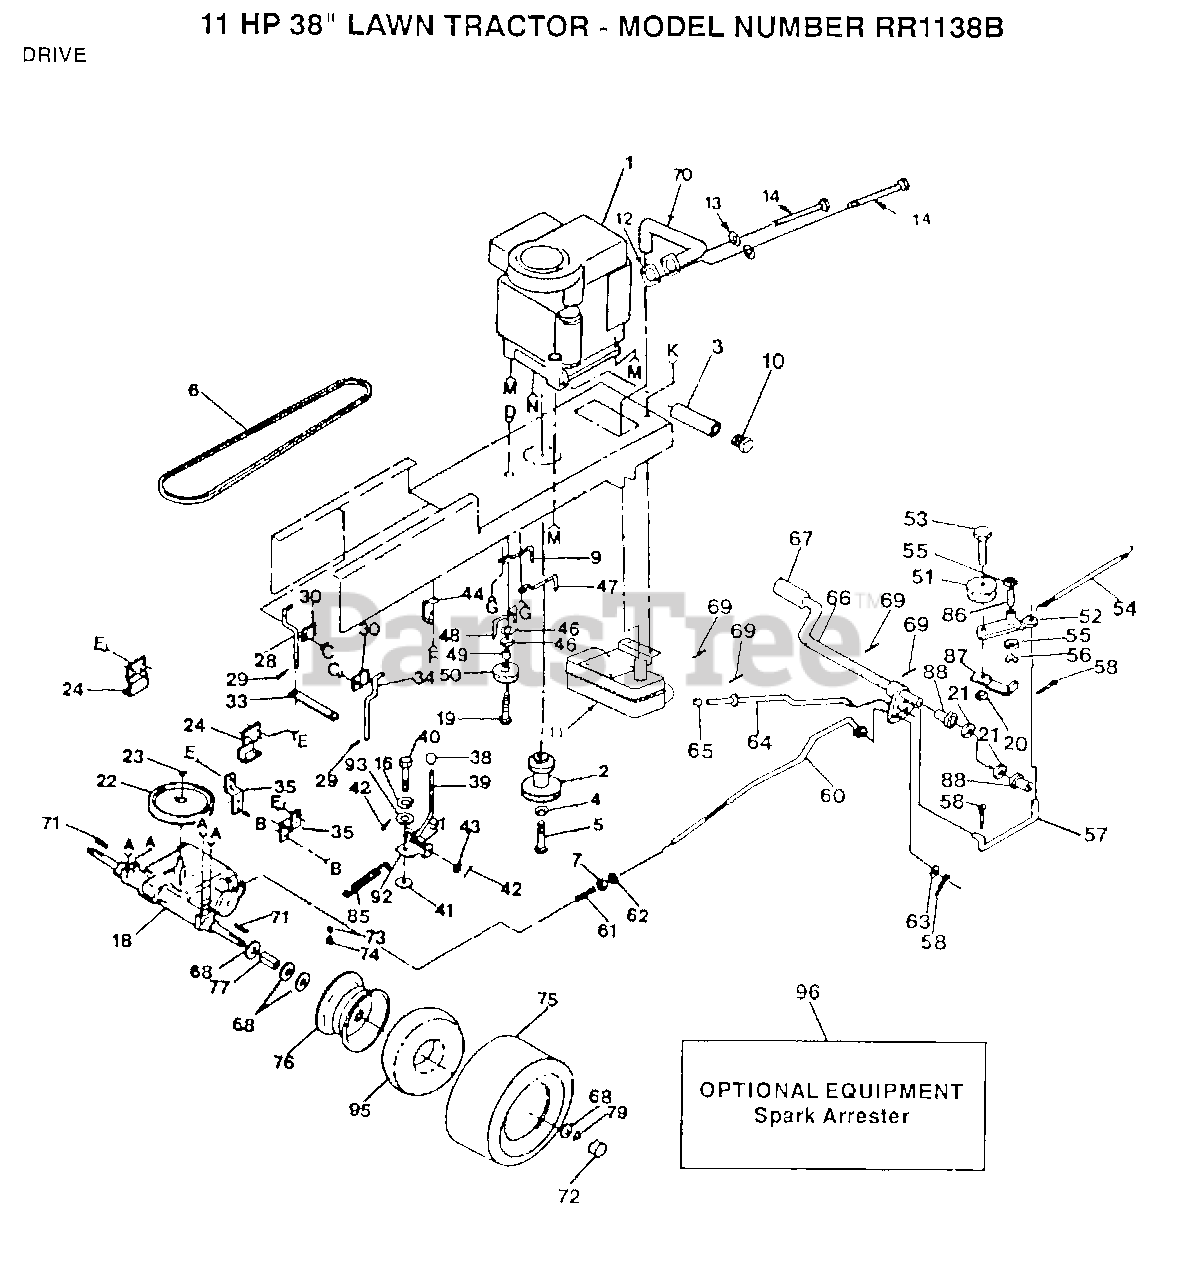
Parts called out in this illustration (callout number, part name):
1	ENGINE BRIGGS AND STRATTON
4	LOCKWASHER
5	BOLT
6	BELT-V.90.0.GD.DR
7	NUT
8	CLIP T
9	KEEPER BELT ENGLH
11	MUFFLER EUROPE
13	LOCKWASHER
14	SCREW LT
15	SCREW
16	LOCKWASHER
19	BOLT
21	WASHER LT
22	PULLEY TRANS
24	BRACKET LT
25	BOLT
26	SCREW
28	KEEPER BELT LH
29	SPRING.RETAINER
30	CLAMP LT
31	BOLT
33	STRAP LOCATOR
34	KEEPER BELTRH
35	STRAP TORQUE
38	KNOB T (1/2-HOLE)
39	ROD SHIFTER
41	WASH-SHFT PLT LT
42	PIN COTTER 1/8
43	WASHER
45	SCREW
46	WASHER
47	"KEEPER,BLT ENG LT"
48	BELT KEEPER LT
49	SPACER T
50	PULLEY.IDLER.FLAT
52	ARM IDLER
54	"SPRING, RETURN LT"
55	WASHER LT
56	KLIP RING
57	"LINK, CLUTCH T"
58	COTTER PIN
60	BRAKE ROD LT
61	SPRING ROD LT
62	NUT
63	WASHER
65	PLUNGER CAP T
67	PEDAL COVER T
68	WASHER
70	PIPE EXHAUST
71	SQUARE KEY
72	HUB CAP
73	VALVE CAP
74	VALVE STEM LT
75	TIRE.TS2.18X8.5
77	SPACER LT
79	E-RING LT
83	WASHER
86	"LY, BEARING"
87	RETAIN BELT
88	NYLON BEARING
91	SPRING LT
92	PLATE SHIFT LT
93	WASHER LT
94	LOCKWASHER
95	TUBE.18X9.5-8
96	SPARK ARREST KIT
97	WASHER
